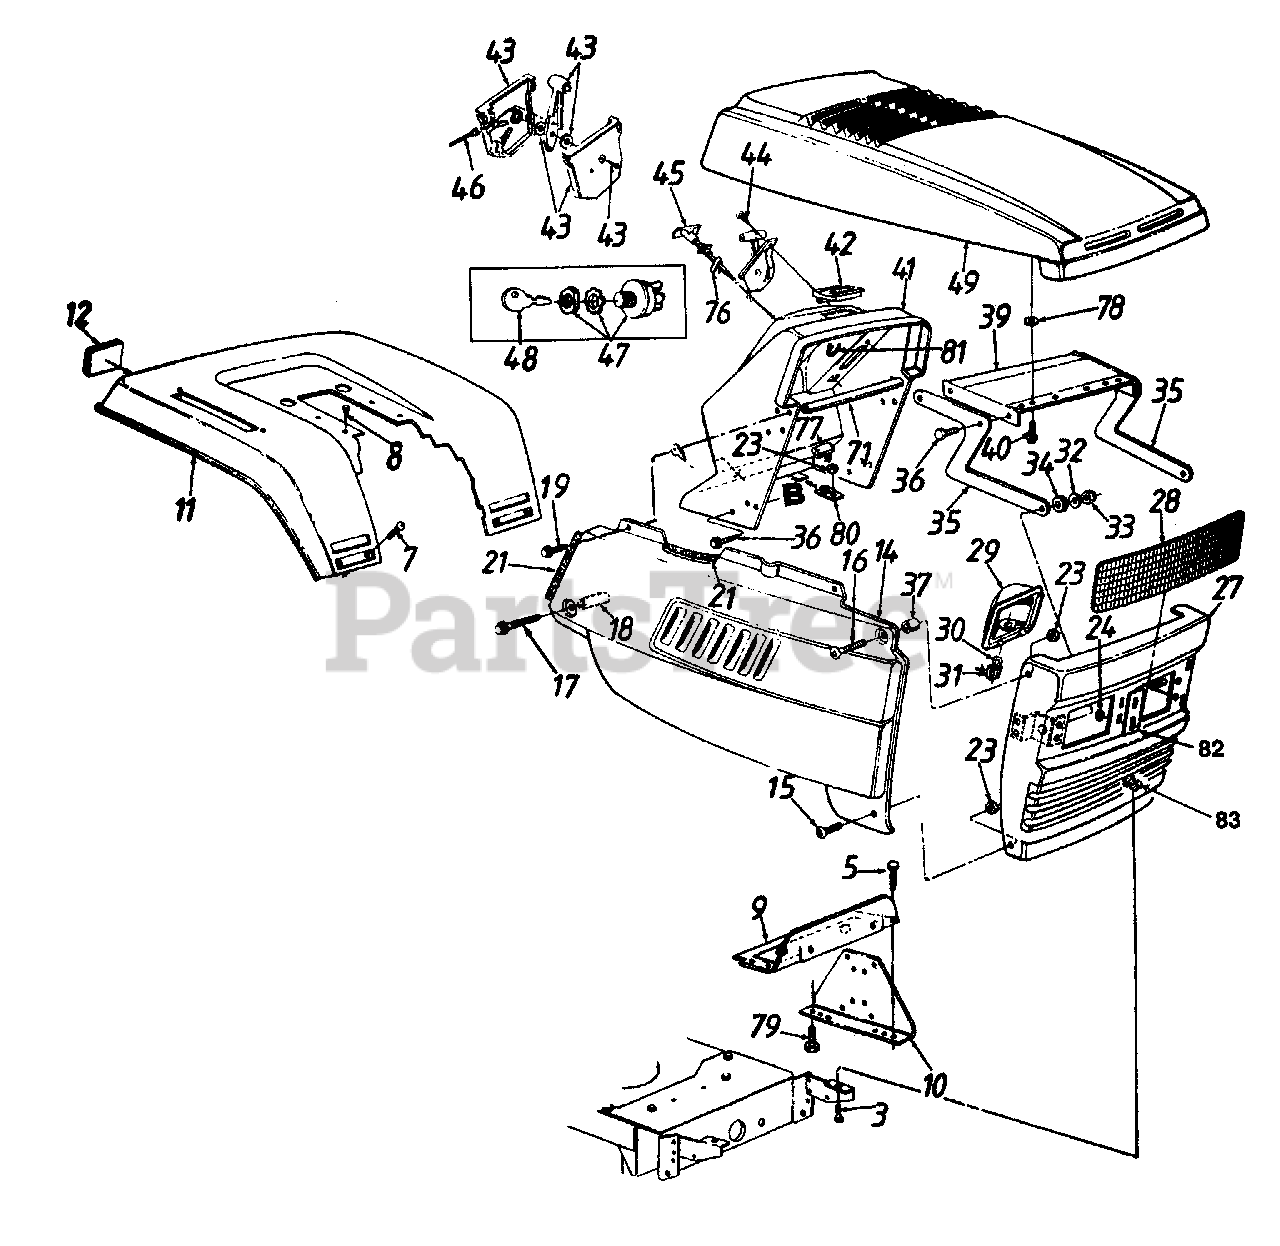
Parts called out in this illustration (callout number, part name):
3	Hex Bolt 5/16-18 x .75" Lg.
5	Hex Wash. Hd. Scr. 5/16" x .5" Lg.
7	Truss Mach. Scr./4-20 x .5" Lg.
8	Hex Wash. Hd. Tap Scr. 5/16 x .75" Lg.
16	Truss Mach. Scr. 1/4-20 x 1.0" Lg.
17	Hex Wash. TT-Tap Scr. 1/4-20 x 1.75" Lg.
18	Spacer .26" I.D. x 1.32"
19	Hex Rolling Tap Scr. 1/4-20 x .75" Lg.
21	Trim Strip-18" Lg.
23	Hex Sems Nut 1/4-20 Thd.
24	Speed Nut 5/16" Thd.
29	Headlamp Housing
30	Headlamp
31	Twin Lock Lamp Socket
32	Bell-Wash..345" I.D. x .88"
33	Hex L-Nut 5/16-18 Thd.
34	Rubber Washer
37	Spacer .262" I.D. x .31"
41	Dash
42	Ammeter
43	Throttle Control Box Ass'y.
44	Mach. Scr. #10 x .44" Lg,
45	Choke Control 23" Lg.
46	Throttle Control Wire 18.5" Lg.
47	Ignition Switch
48	Ignition Key
49	Hood-Red
71	Grille Support Tube
76	Choke Retainer
77	Light Switch
78	Fl-Wash..406" I.D. x .812" O.D.
79	Hex Bolt 1/4-20 x .88" Lg.
80	Dash Fastening Tab
81	Cable Tie
82	Chrome Label
83	U-Nut 5/16-18 Thd.
